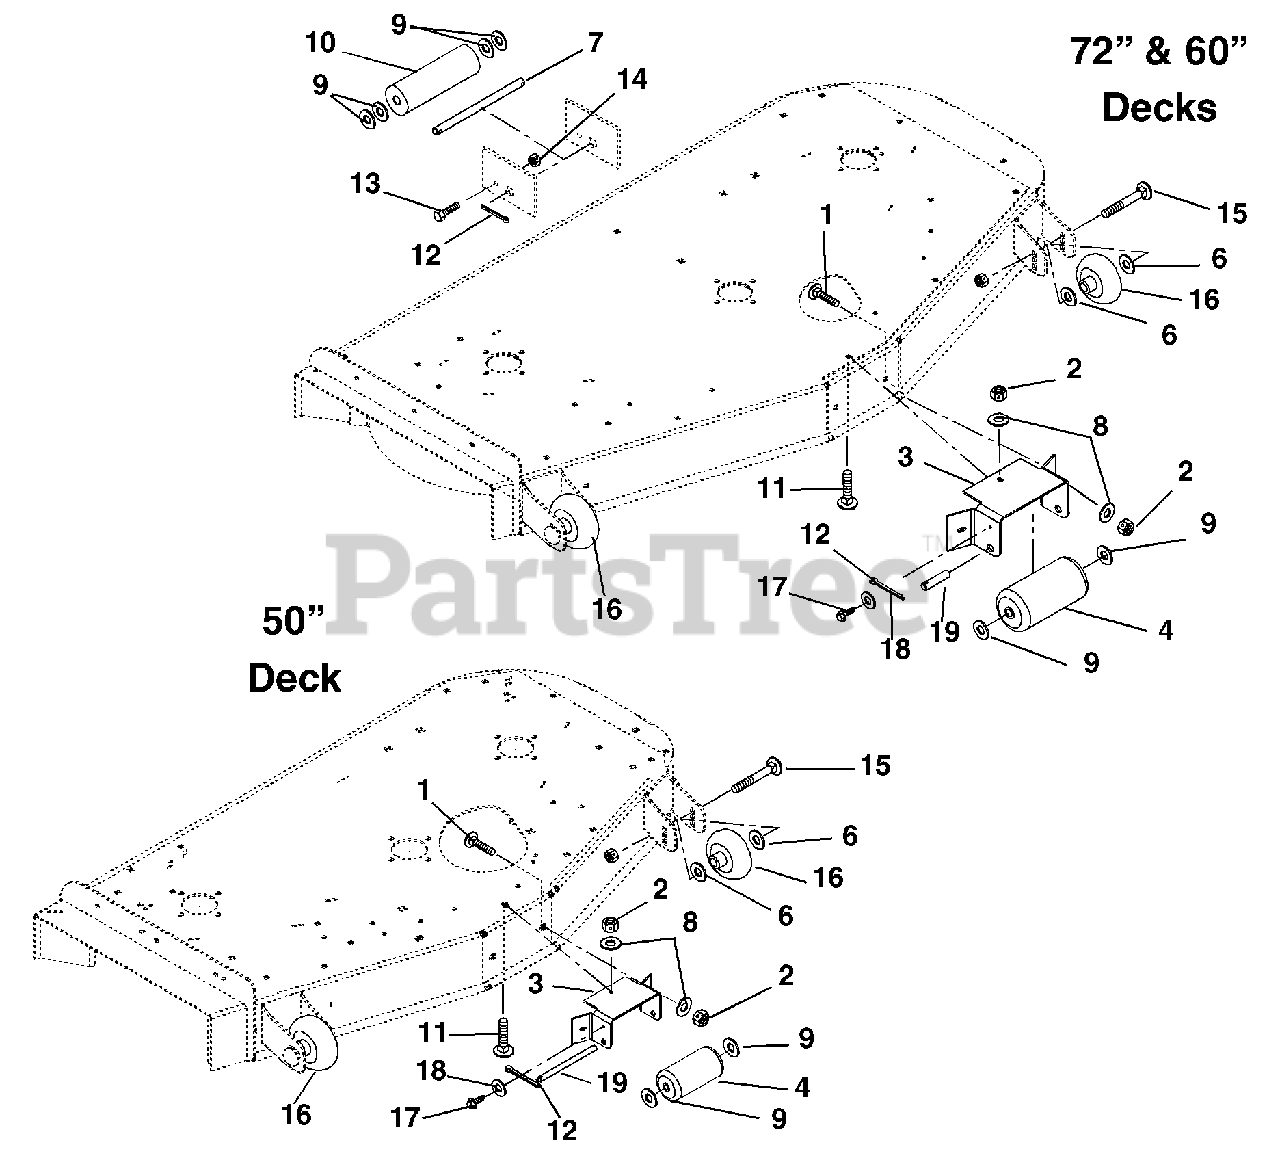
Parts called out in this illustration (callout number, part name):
1	Bolt-Round Head Square Neck .38-16 x 1.00 Grade 5)
2	Nut-Locking-Nylon .38-16
3	Bracket, Anti-Scalp Roller
5	Nut-Locking-Nylon .50-13
6	Washer-Flat-Steel .531 x 1.06 x .095
7	Shaft, Center Roller (60" & 72" Deck)
8	Washer-Flat-Steel .406 x .812 x .065
9	Washer-Flat-Steel .656 x 1.31 x .095 (72" & 60" Deck)
9	Washer-Flat-Steel .656 x 1.31 x .095 (50" Deck)
10	Roller, Gage (60" & 72" Deck)
11	Bolt-Round Head Square Neck .38-16 x 1.25 Grade 5
12	Pin-Cotter .25 x 2.00 (72" & 60" Deck)
12	Pin-Cotter .25 x 2.00 (50" Deck)
13	Bolt-Hex .25-20 x .75 Grade 5 (72" & 60" Deck)
14	Nut-Locking-Center .25-20 (72" & 60" Deck)
15	Bolt-Round Head Square Neck .50-13 x 5.00 Grade 2
16	Wheel, 3 x 5
17	Screw-Self Tapping .25-20 x .50 x Hex Washer Head
18	Washer-Flat-Steel .281 x .62 x .065
